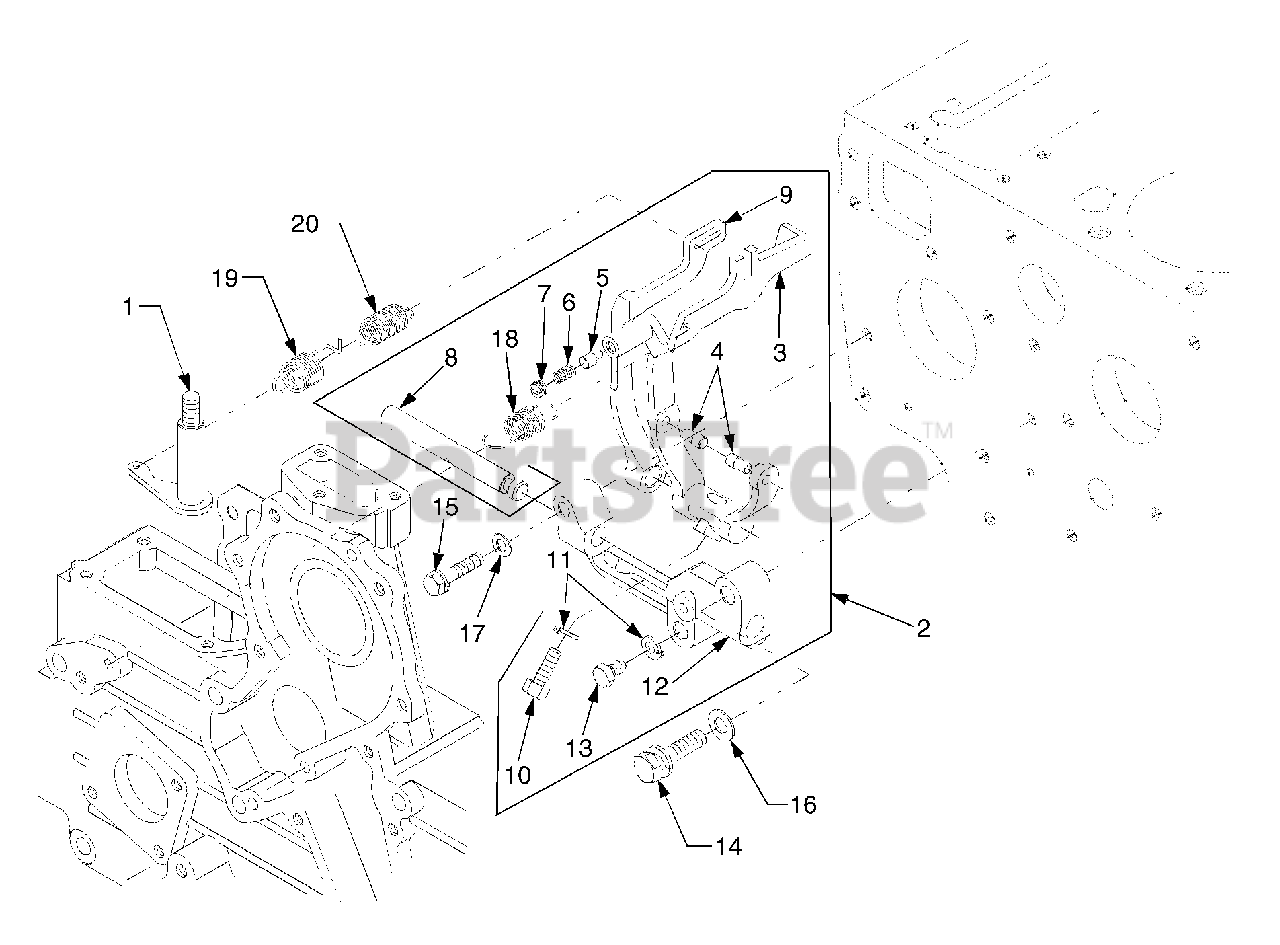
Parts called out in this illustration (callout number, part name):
1	Governor Lever Ass'y
2	Fork Lever Ass'y
3	Lever 1, Fork
4	Pin, Fork Lever
5	Pin
6	Spring
7	Screw, Set
8	Shaft, Fork Lever
9	Lever 2, Fork
10	Bolt
11	Washer, Spring
12	Holder, Fork Lever
13	Bolt
16	Washer, Plain
17	Washer, Plain
18	Spring, Start
19	Spring 1, Governor
20	Spring 2, Governor
